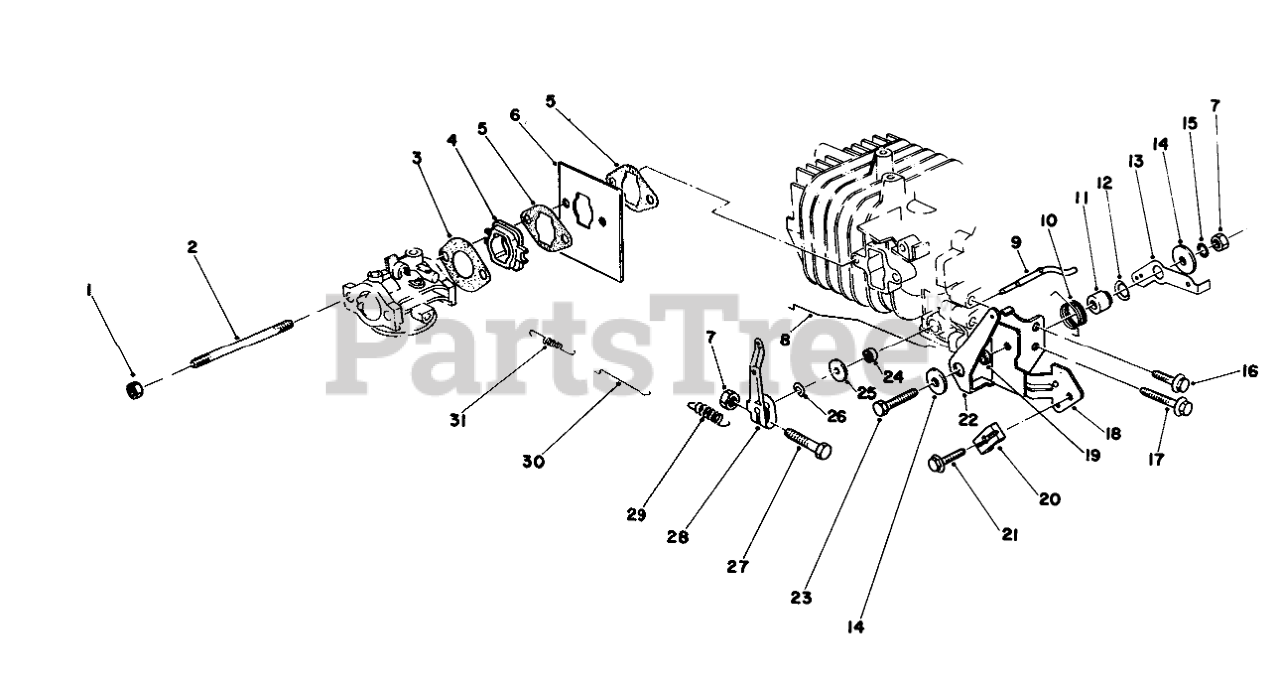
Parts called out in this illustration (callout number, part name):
1	NUT-LOCK
2	CARB STUD BOLT
3	GASKET-CARB
4	INSULATOR
5	GASKET
6	SHIELD
8	CHOKE ROD
9	Shaft-Govemor
10	Spring-Choke Control Lever
11	Gov Lever Spacer
12	Washer-Gov. Spring Lever
13	GOV SPRING LEVER
14	WASHER
15	LOCKWASHER
18	Bracket-Throttle Control
19	Spacer-Choke Control Lever
20	CLAMP-CABLE
22	LEVER-CONTROL, CHOKE
24	SEAL-OIL
25	WASHER
26	E-RING
28	Lever-Throttle Control
29	GOVERNOR SPRING
30	ROD-CARBURETOR
31	SPRING
